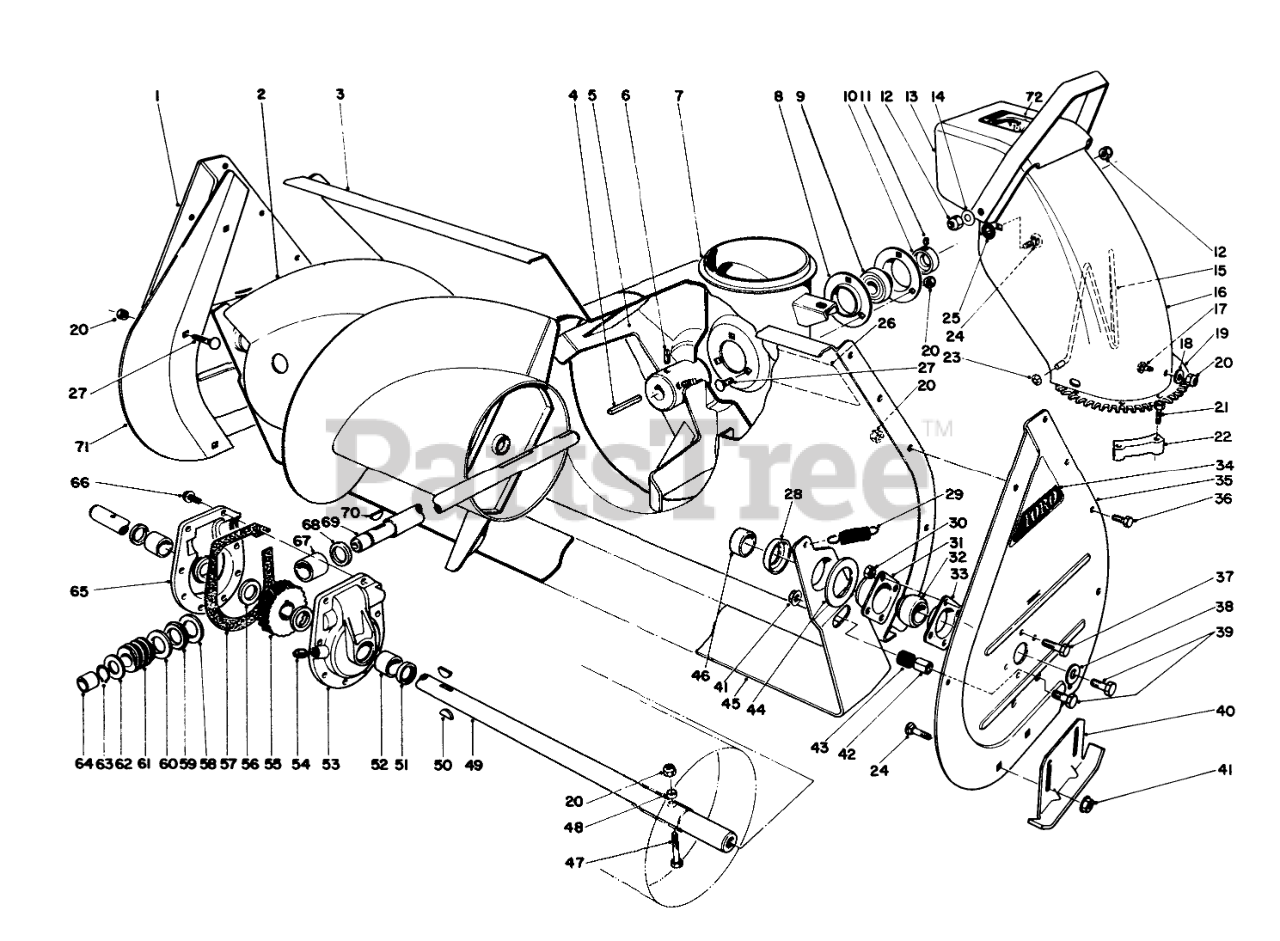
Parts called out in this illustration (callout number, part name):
1	RH AUGER SIDE PLT R
2	RH AUGER ASM - 32"
3	Auger Housing
5	IMPELLER ASM
6	SCREW-SET, SQH
7	CHUTE RING
8	BRG FLANGE
9	Bearing-Impeller (Incl. Ref.10 & 11)
10	EXT LOCKING COLLAR
11	SCREW-HSH
12	NUT-LOCK, CONE
13	Deflector
14	WASHER-BELLEVILLE
15	WIRE-CHUTE
16	Upper Chute
17	SCREW-CARR
18	WASHER-PLAIN
19	Screw
20	NUT-LOCK, NI
21	SCREW-SPECIAL
22	RETAINER-CHUTE
23	NUT-PUSH
24	SCREW-CARR
25	WASHER-RUBBER
26	Decal-Warning
27	BOLT-CARR
28	Positioner-Scraper
29	SPRING-TENSION
30	NUT-LOCK, CONE
31	BEARING-FLANGE, FRONT
32	BEARING
33	BEARING-FLANGE, REAR
34	AUGER SIDE PLT DECAL
35	LH AUGER SIDE PLT R
36	SCREW-HH
37	SCREW-HH
38	WASHER
39	SCREW-HH
40	AUGER SKID WA R
41	NUT-HF
42	SCRAPER STOP SPACER
43	SCRAPER STOP CUSHION
44	SCRAPER BLADE SPACER
45	SCRAPER BLADE 32" R
46	AUGER SPACER
47	Auger Bolt
48	SPACER-HUB, AUGER
49	32 AUGER SHAFT
50	KEY-WOODRUFF
51	SEAL-OIL
52	BUSHING
53	Gear Case Bushing Assy.-L.H. (Incl. Ref. #51, 52)
54	PLUG-PIPE, SQH
55	GEAR-WORM, 27T
56	WASHER-THRUST
57	GASKET-CASE, GEAR
58	WASHER-THRUST
59	BEARING-THRUST
60	THRUST-WASHER
62	WASHER-THRUST
63	Ring-Snap
64	BUSHING
65	Gear Case Bushing Assy.-R.H. (Incl. Ref. #51, 52)
66	SCREW-TAPTITE
67	BUSHING-SPECIAL
68	RING-QUAD
69	SHAFT-IMPELLER
70	KEY-WOODRUFF
71	Auger Housing Extension R.H.
72	Decal-Danger
